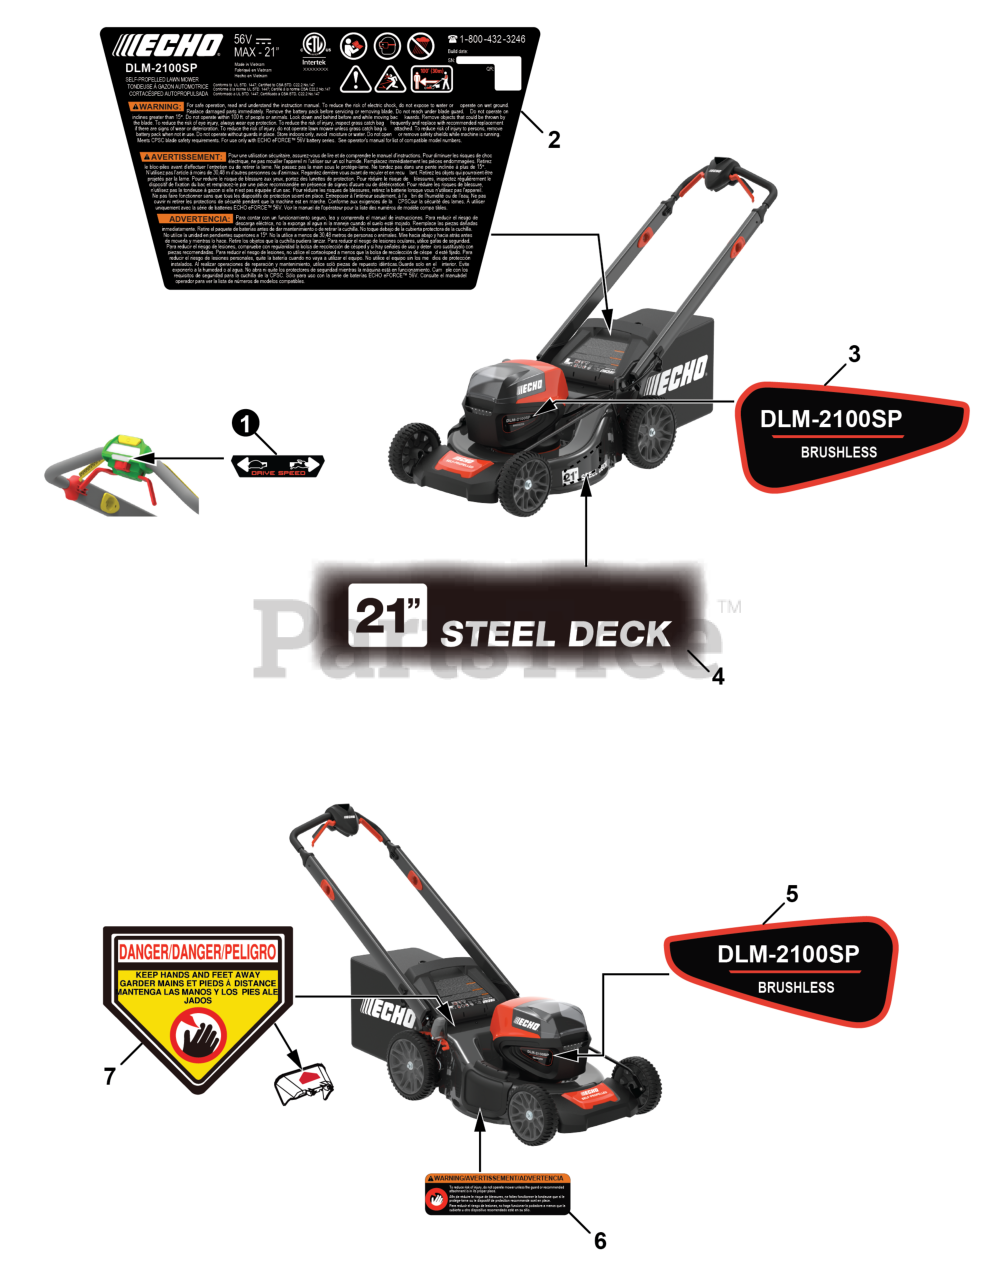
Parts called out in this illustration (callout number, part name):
1	LABEL,ADJUSTING
2	LABLE,WARNING\SERIAL - VIETNAM
3	BRAND LOGO,LEFT DECK
4	LOGO,21" STEEL DECK
5	BRAND LOGO,RIGHT DECK
6	LABEL,SIDE WARNING
7	LABEL,WARNING
